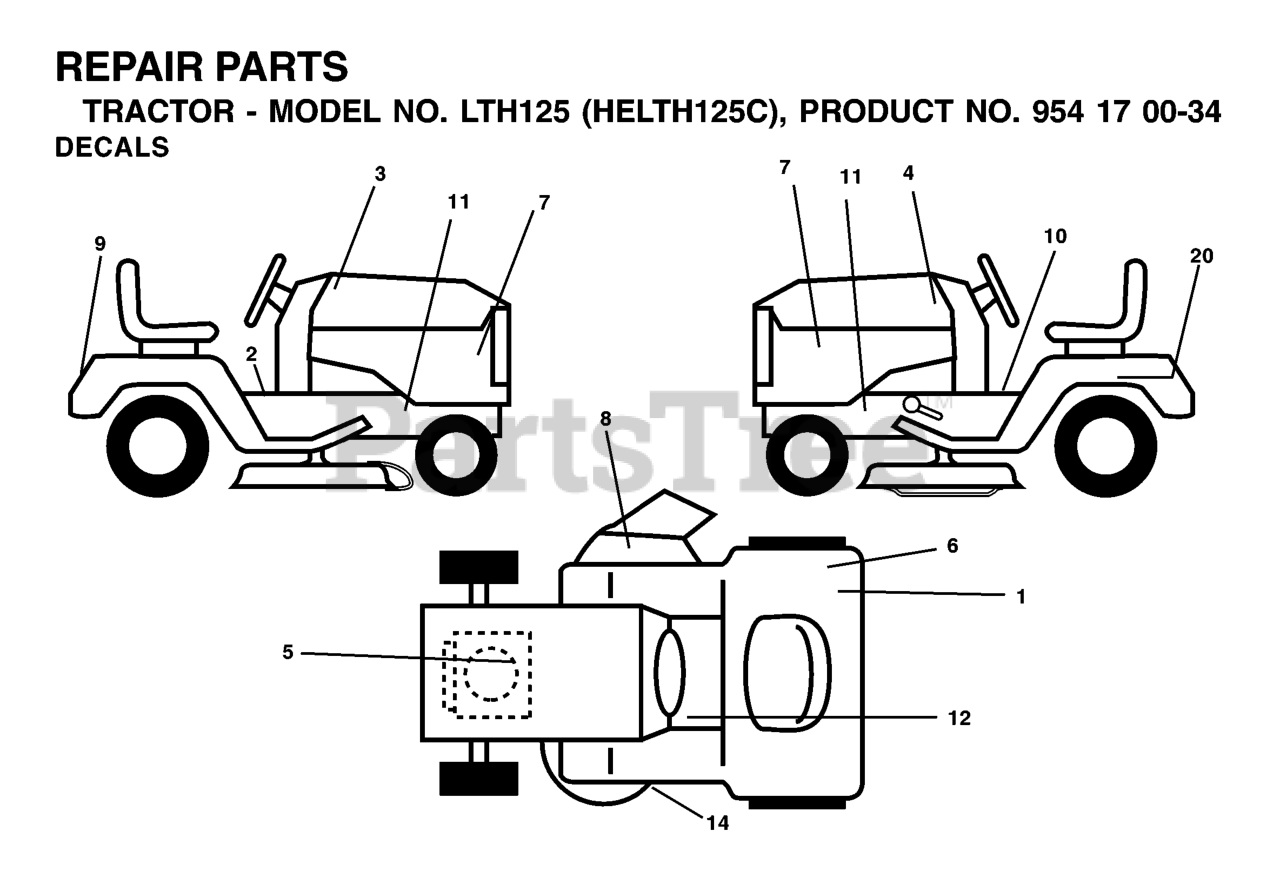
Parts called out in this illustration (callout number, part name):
1	DECAL CERTIFICATION
2	DECAL PARK BRAKE
5	DECAL ENGINE HP
6	DECAL EUROPE STANDARD CE
7	DECAL PNL SIDE
8	DECAL MOWER CUT/FINGER
9	DECAL FENDER HUSQ
10	DECAL READ OWNER'S MAN SYMS
12	DECAL
14	DECAL V-BELT SCHEMATIC
20	DECAL BTRY SYMBOLS
